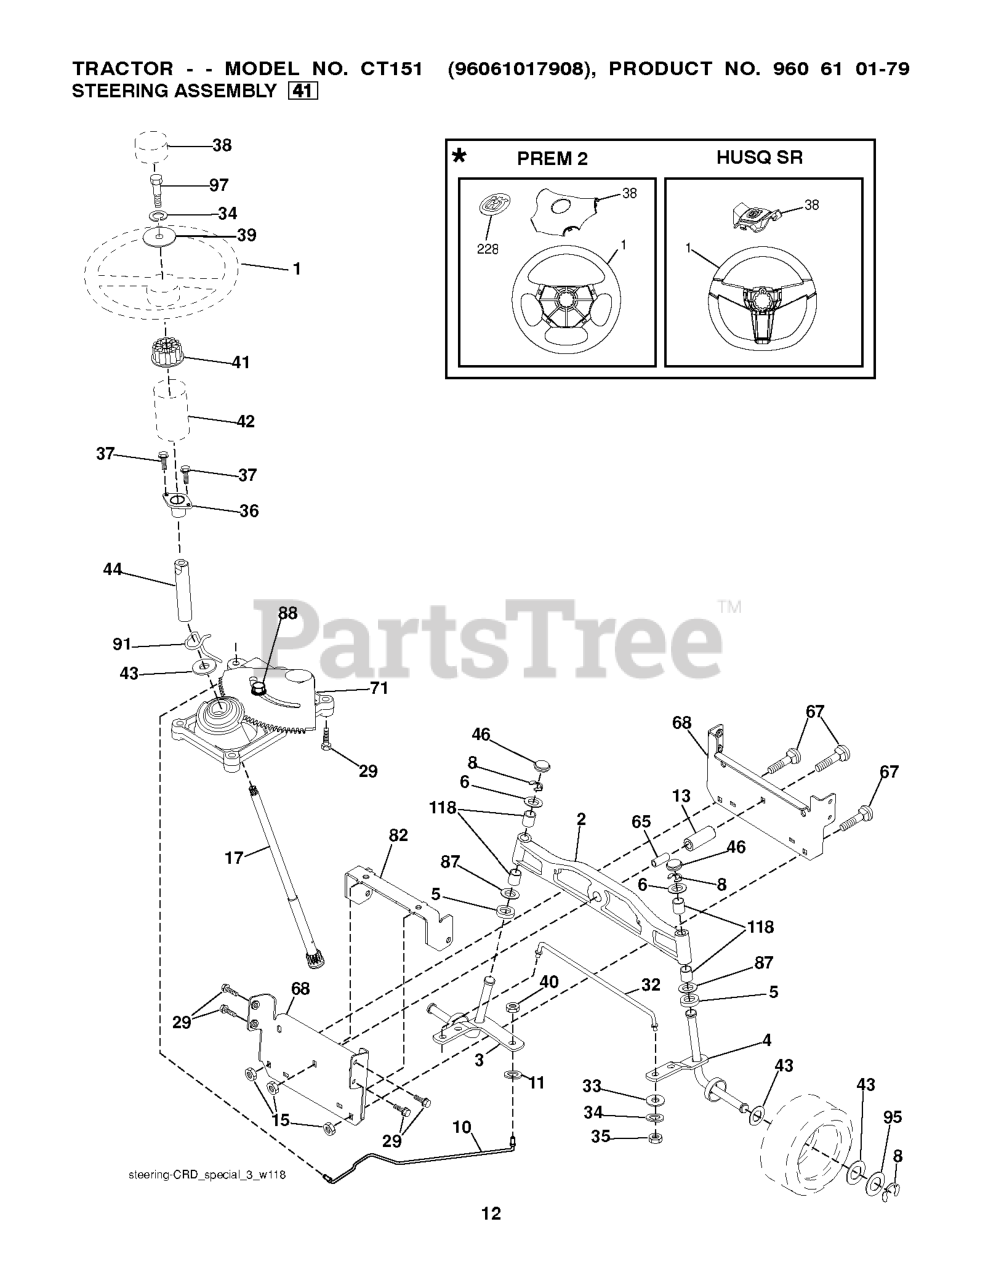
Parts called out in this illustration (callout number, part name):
1	RP WHEEL.STEER.HUSQ.PREM.OVMLD
2	AXLE.ASM.LT.CAST.LGHTWGHT
3	SPINDLE.ASM.LH.15"TIRES
4	SPINDLE.ASM.RH.15"TIRES
5	THRUST WASHER
10	DRAGLINK.15".TIRES.2001
11	WASHER, LOCK 3/8
13	TUBE, PIVOT AXLE
15	NUT
17	SHAFT STEERING SPLINE
29	SCREW, 3/8-16X3/4
33	WASHER M
34	WASHER.LOCK.HVY.HLCL.SPR.5/16
35	NUT, CROWNLOCK
36	BUSHING, STEERING
37	SCREW.TT.#10-32X.5.3/8.FLANGE
38	RP INSERT.CAP.WHL.STRG.HUSQ.
39	WASHER.11/32
40	NUT CROWNLOCK 3/8-24
41	ADAPTER, WHEEL STNG..
42	BOOT, STEERING
44	SHAFT.EXTEN.STRG.SPLINE
46	CAP.SPINDLE.BLACK
65	SPACER.BRACE.AXLE
67	BOLT CARRIAGE
68	BRACE.AXLE.15"TIRES
71	STEERING ASM
82	BRACKET.SUSP.CHASSIS.FRONT.15
87	WASHER, FLAT .781 X 1 1/2"
88	BOLT, SHOULDER 7/16-20
91	CLIP.STEERING
95	WASHER.HARDENED
118	BUSHING, AXLE CAST
228	DECAL.WHEEL.STRG.LGN.H
